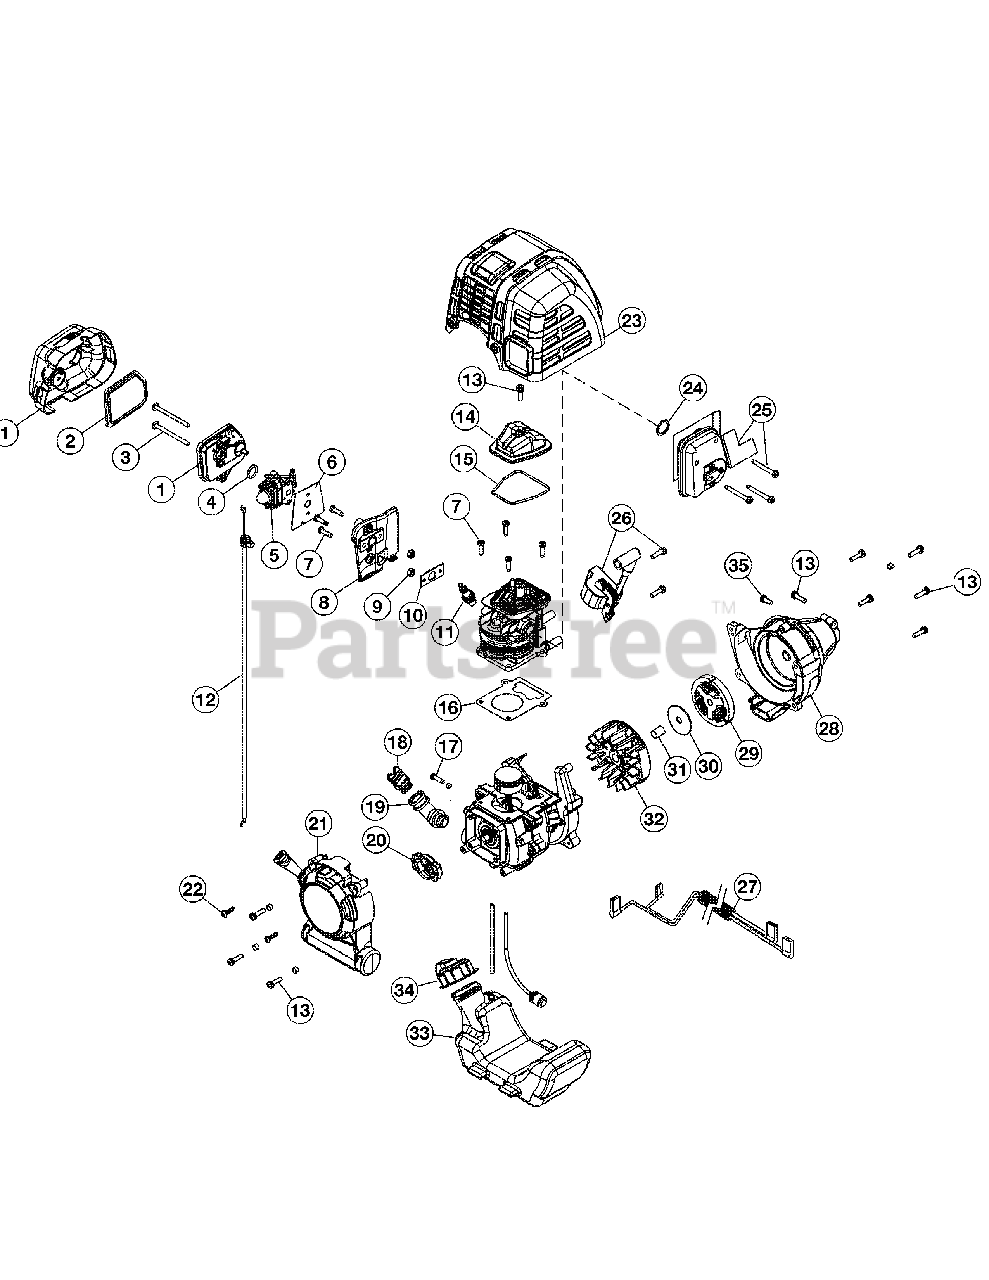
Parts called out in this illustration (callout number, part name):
1	Aircleaner Assembly
2	Air Filter
4	Carburetor O-Ring
5	Carburetor Assembly
6	Carburetor Gasket
7	Screw
10	Insulator Gasket
11	Spark Arrestor
12	Throttle Cable
14	Valve Cover
15	Valve O-Ring
16	Cylinder Gasket
18	Oil Plug Assembly
19	Oil fill Tube Assembly
20	Pawl Assembly
21	Rear Starter Cover Assembly
23	Starter Housing
24	Muffler Gasket
25	Muffler Assembly
26	Module Assembly
27	Lead Wires
28	Clutch Cover Assembly
30	Clutch Washer
33	Fuel Tank
35	Anti-Rotation Screw
